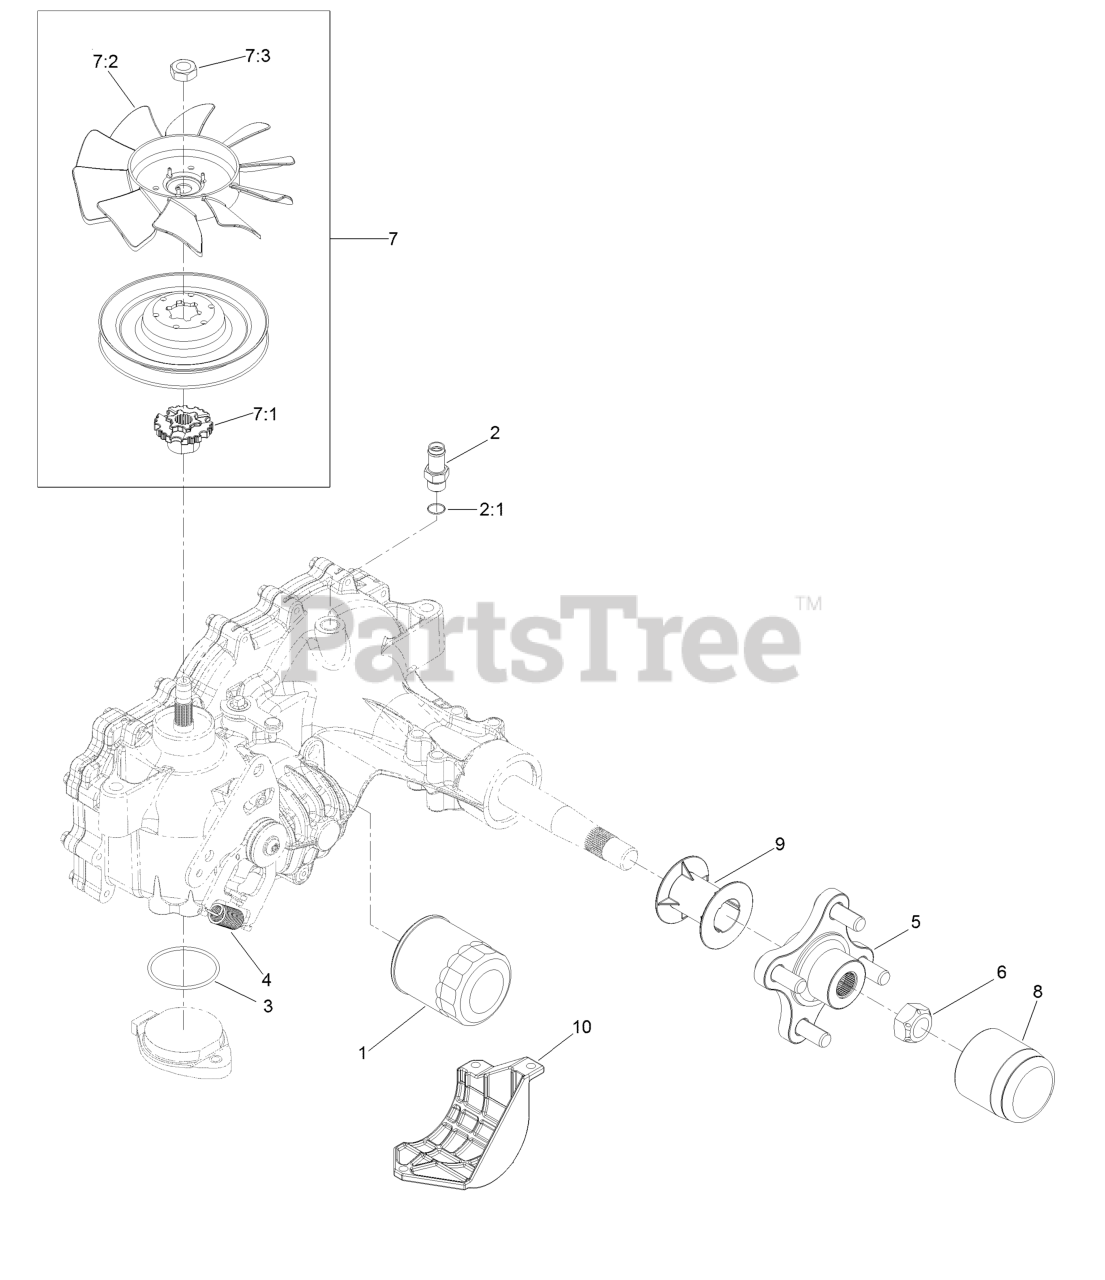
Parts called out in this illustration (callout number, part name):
1	Element-Oil Filter, HYD
2	Adapter-Straight
2:1	O-Ring
3	O Ring-Seal
4	Spring-Extension
5	Hub-Offset
6	Nut-Hub
7	Fan And Pulley Kit
7:1	Hub-Fan
8	Cap-Axle, Long
9	Tube-Axle
10	Guard-Filter, LH
99	Brake Shaft Seal Kit
99	Seal Kit
